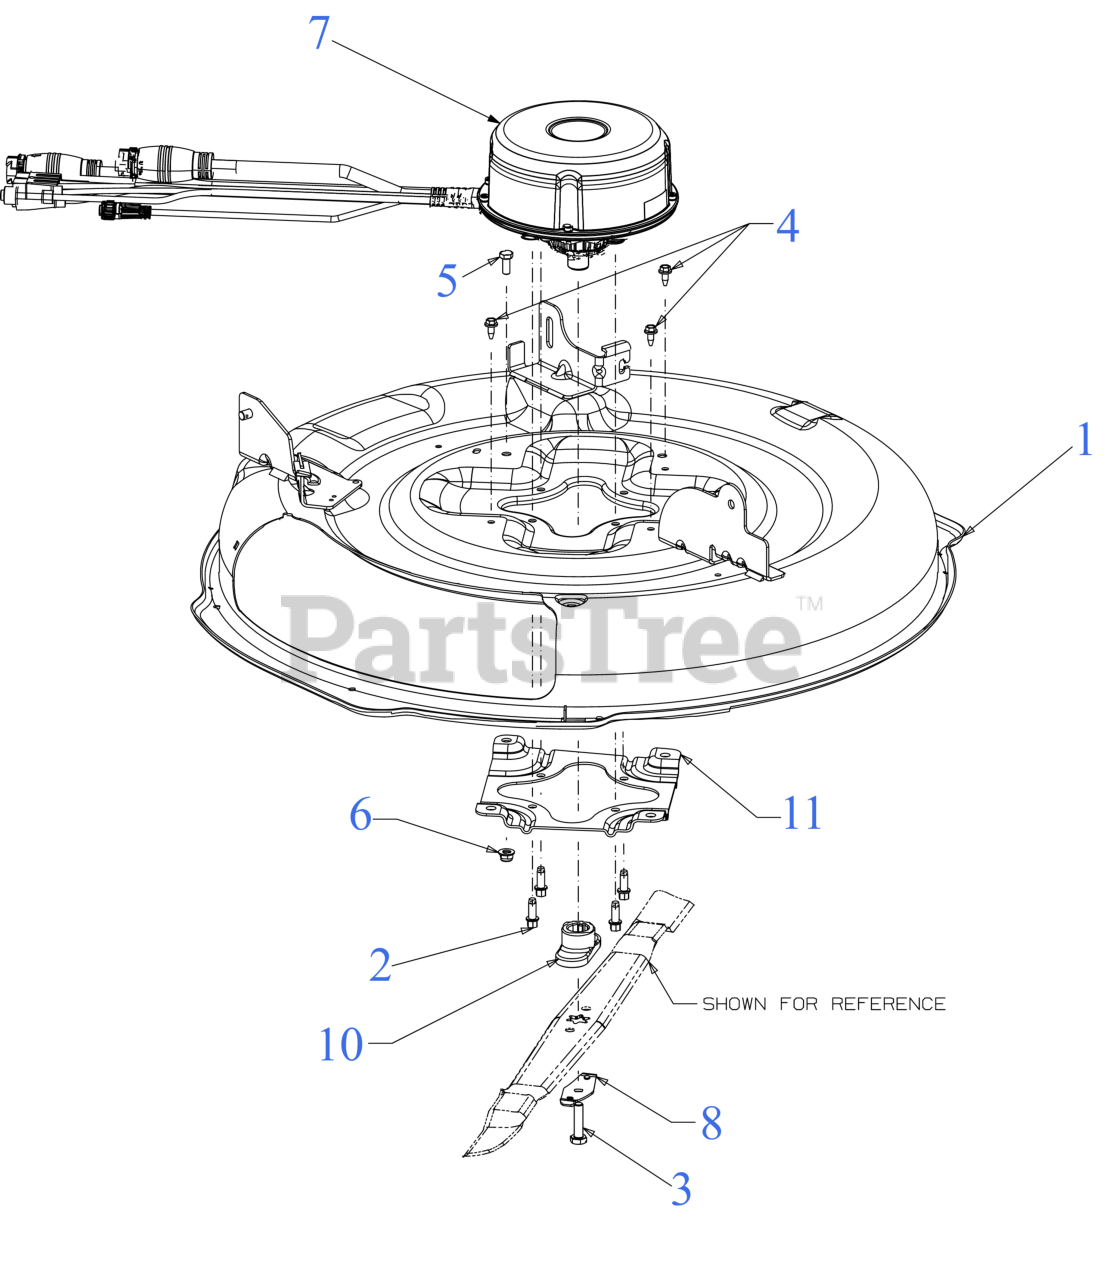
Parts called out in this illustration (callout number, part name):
1	30" DECK ASSEMBLY (W/O NOZZLE)
2	SCREW 5/16-18 x .875
3	SCREW 3/8-24 x 1.50 GR8
4	SCREW 1/4-20X.625
5	SCREW 5/16-18 x .75 GR5
6	FLANGE LOCK NUT 5/16-18
7	48V ELECTRIC DECK MOTOR
8	BLADE BELL SUPPORT
10	BLADE ADAPTER (#6 x 1.19 W/STAR)
